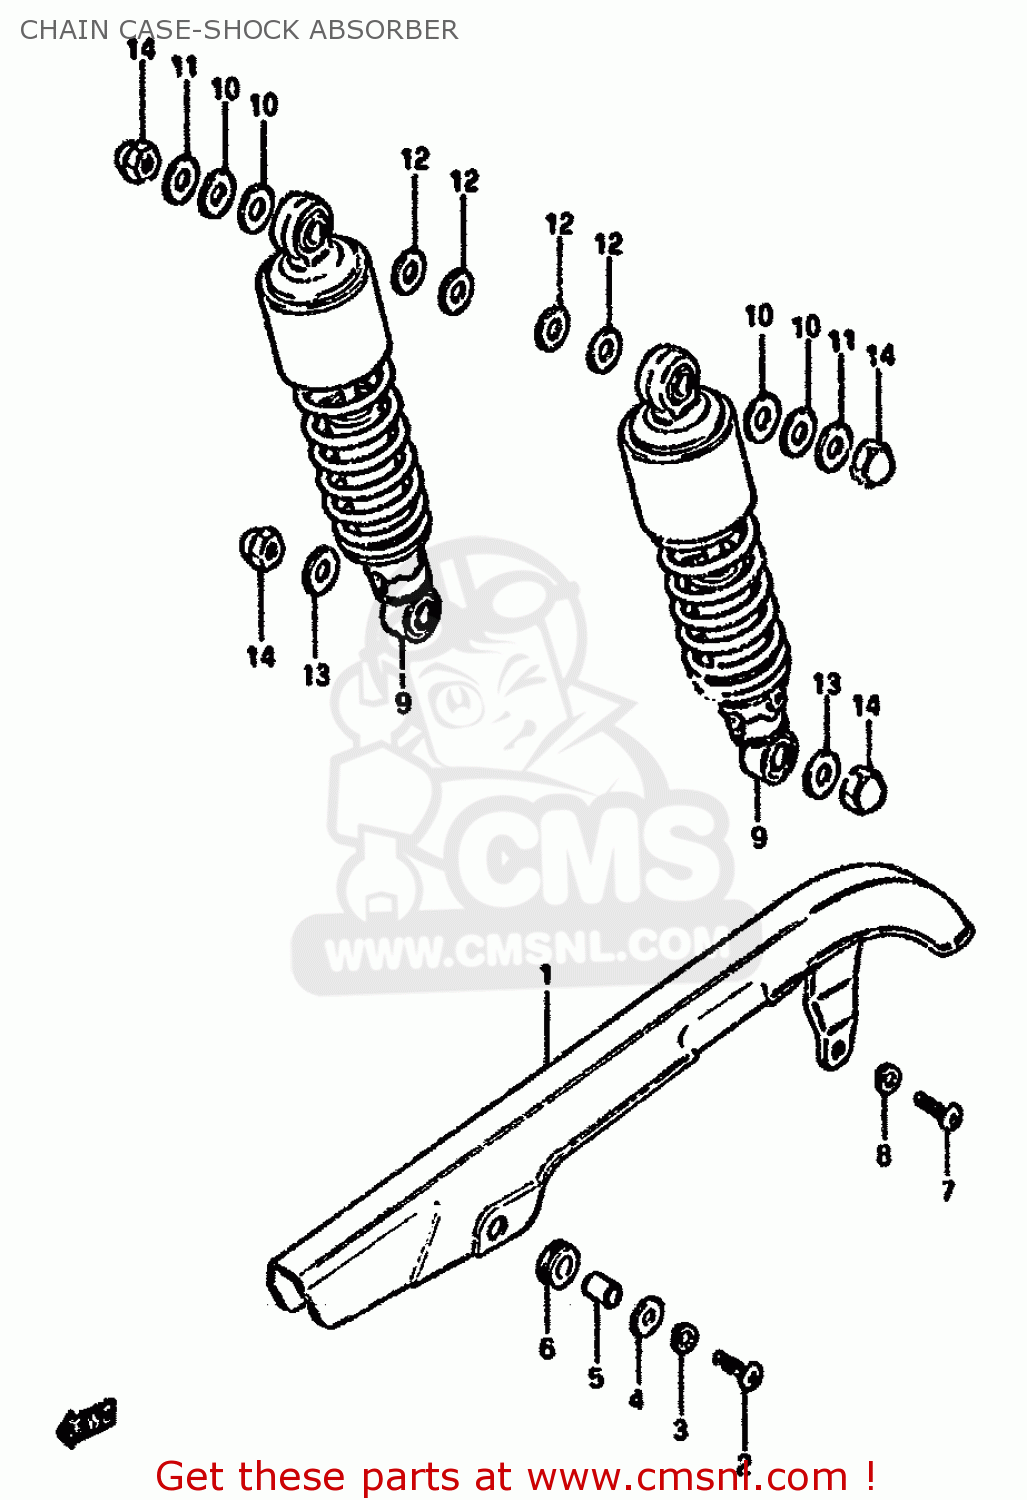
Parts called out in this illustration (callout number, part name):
1	CASE,CHAIN
2	SCREW
3	WASHER,LOCK
4	WASHER (6.5X20X1.2)
5	SPACER (7X9X7)
6	CUSHION
7	SCREW
8	WASHER,LOCK
9	ABSORBER ASSY,RR SHOCK
10	WASHER
11	WASHER(10.5X24X3.2)
12	WASHER
13	WASHER
14	NUT
